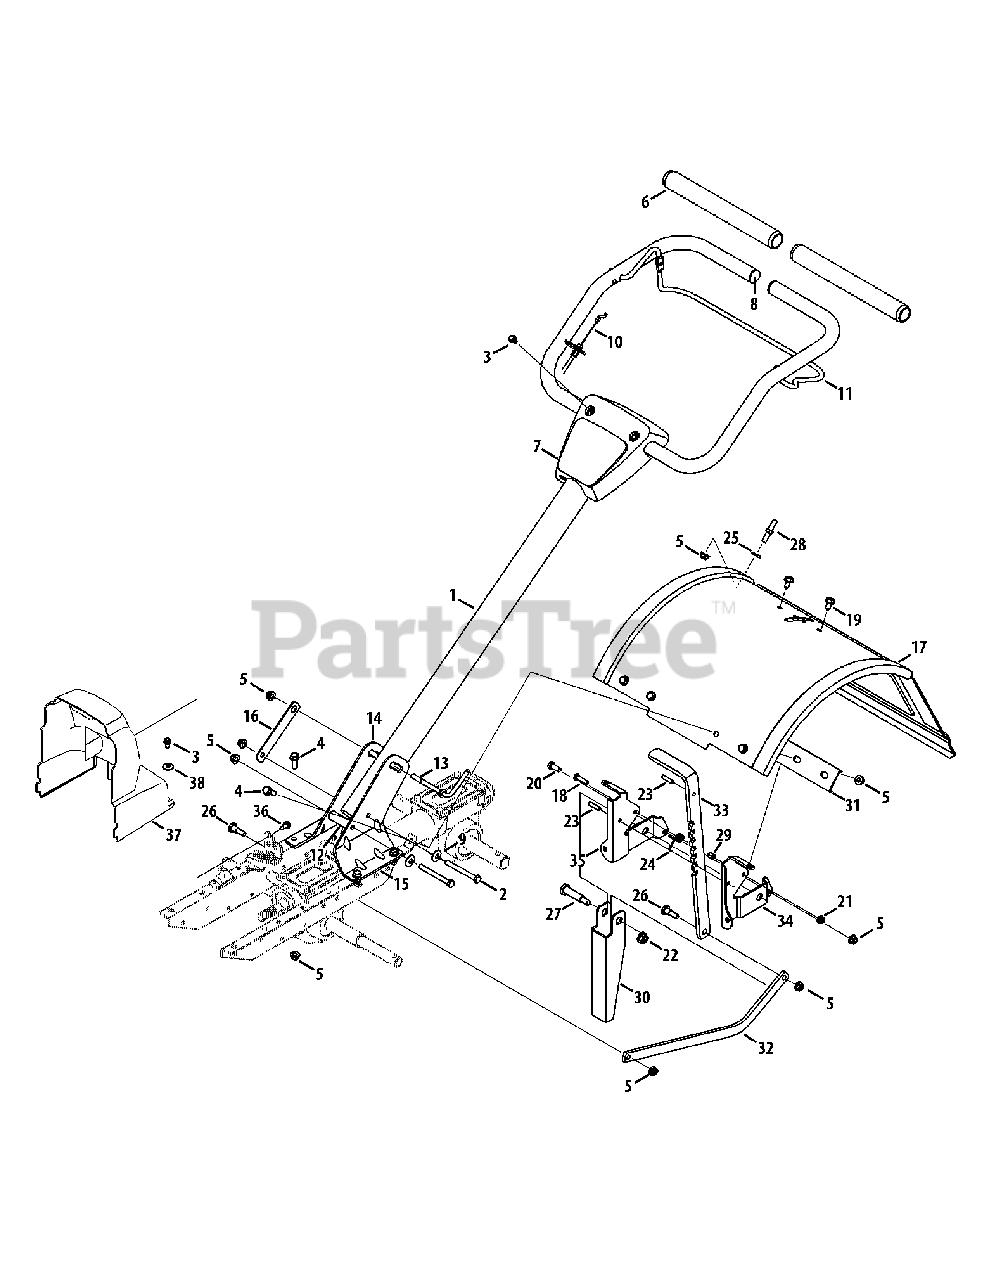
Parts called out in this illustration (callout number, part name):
1	Upper Handle Assembly
2	Hex Head Screw, 5/16-18 x 3.00
3	Self-Tapping Screw, 1/4-20 x 1/2
4	Hex Head Screw, 5/16-18 x .875
5	Nylon Hex Lock Nut, 5/16-18
6	Foam Handle Grip
7	Handle Cover
8	Plug End
9	Bell Washer, .340 x .872 x .060
10	Forward Cable
11	Clutch Bail
12	Spacer, .322 x .625 x 2.00
13	Handle Crank
14	Handle Bracket, RH
15	Handle Bracket, LH
16	Retainer Nut Bracket
17	Tine Shield Assembly
18	Hex Head Screw, 1/4-20 x 1
19	Hex Head Screw, 5/16-18 x .625
20	Hex Head Screw, 5/16-18 x .75
21	Nylon Hex Lock Nut, 1/4-20
22	Flange Lock Nut, 3/8-16
23	Spirol Pin
24	Torsion Spring
25	Flat Washer, .344 x .750 x .120
26	Shoulder Screw, .405 x .435 5/16-18
27	Shoulder Screw, .498 x 1.635
28	Stop Screw
30	Reverse Stop Arm
31	Support Bracket
33	Adjustable Depth Bar
34	Tail Bracket, LH
35	Tail Bracket, RH
36	Self Tapping Screw, 1/4-14 x .625
37	Belt Cover
38	Flat Washer, .28 x .74 x .063
